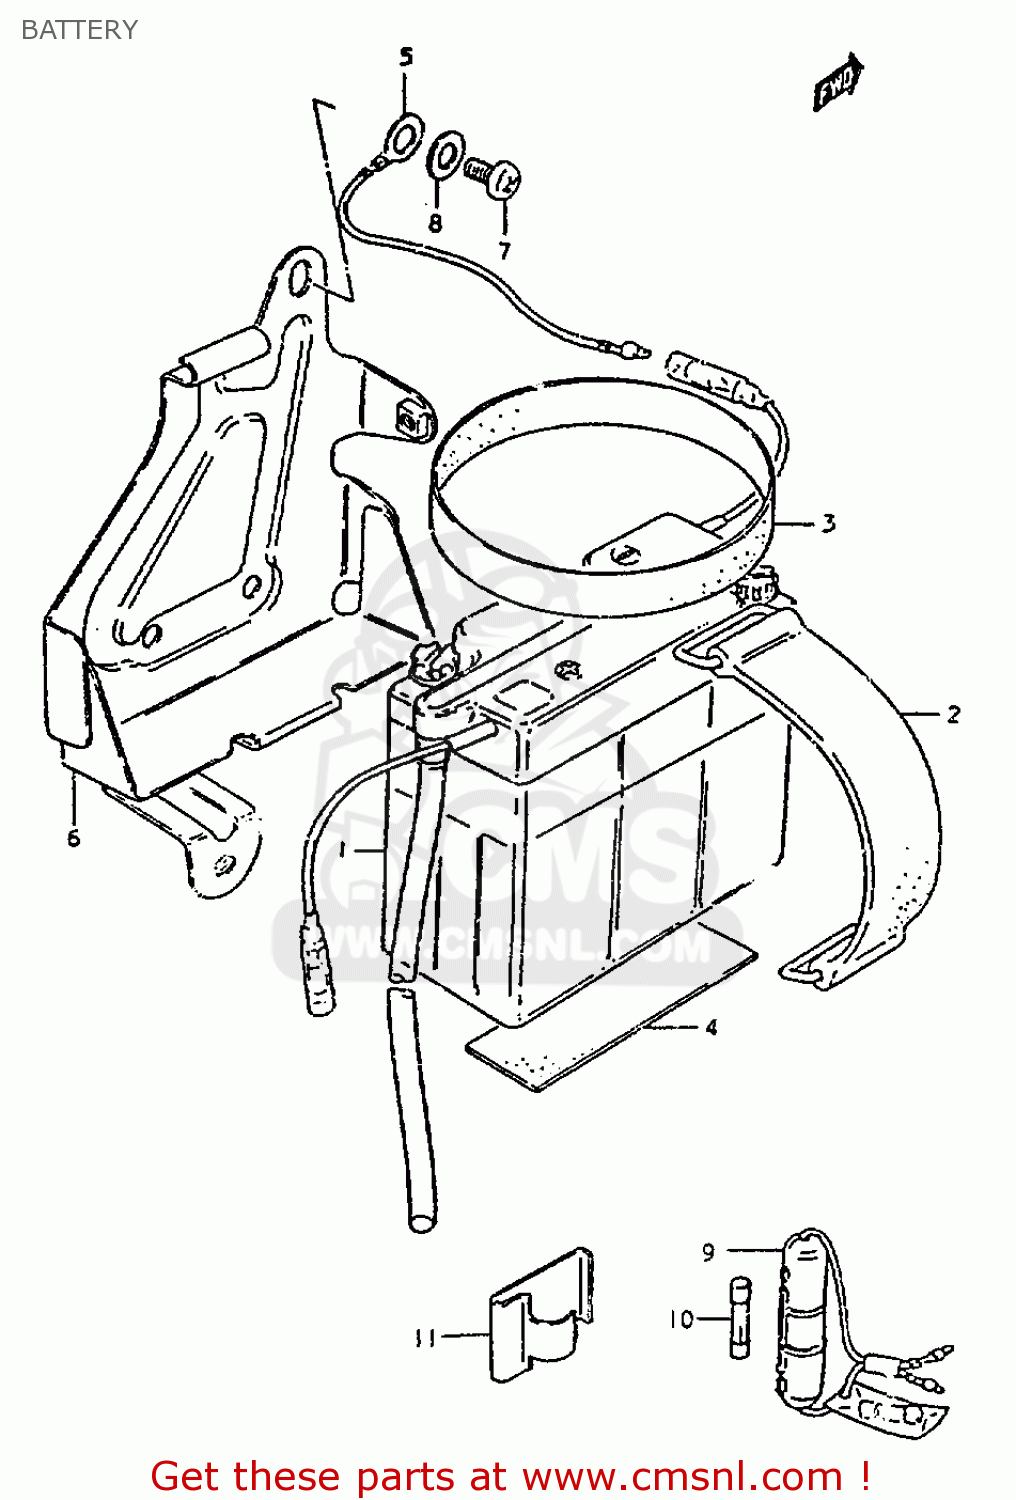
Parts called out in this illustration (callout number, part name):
1	BATTERY(6N4B-2A,6V4.2AH)
2	BAND
3	PROTECTOR,BATTERY
4	PROTECTOR(170X95X3.0)
5	LEAD WIRE
6	HOLDER, BATTERY
7	SCREW 6X12
8	WASHER
9	BOX ASSEMBLY,FUSE
10	FUSE(10A)
11	HOLDER,FUSE CASE
